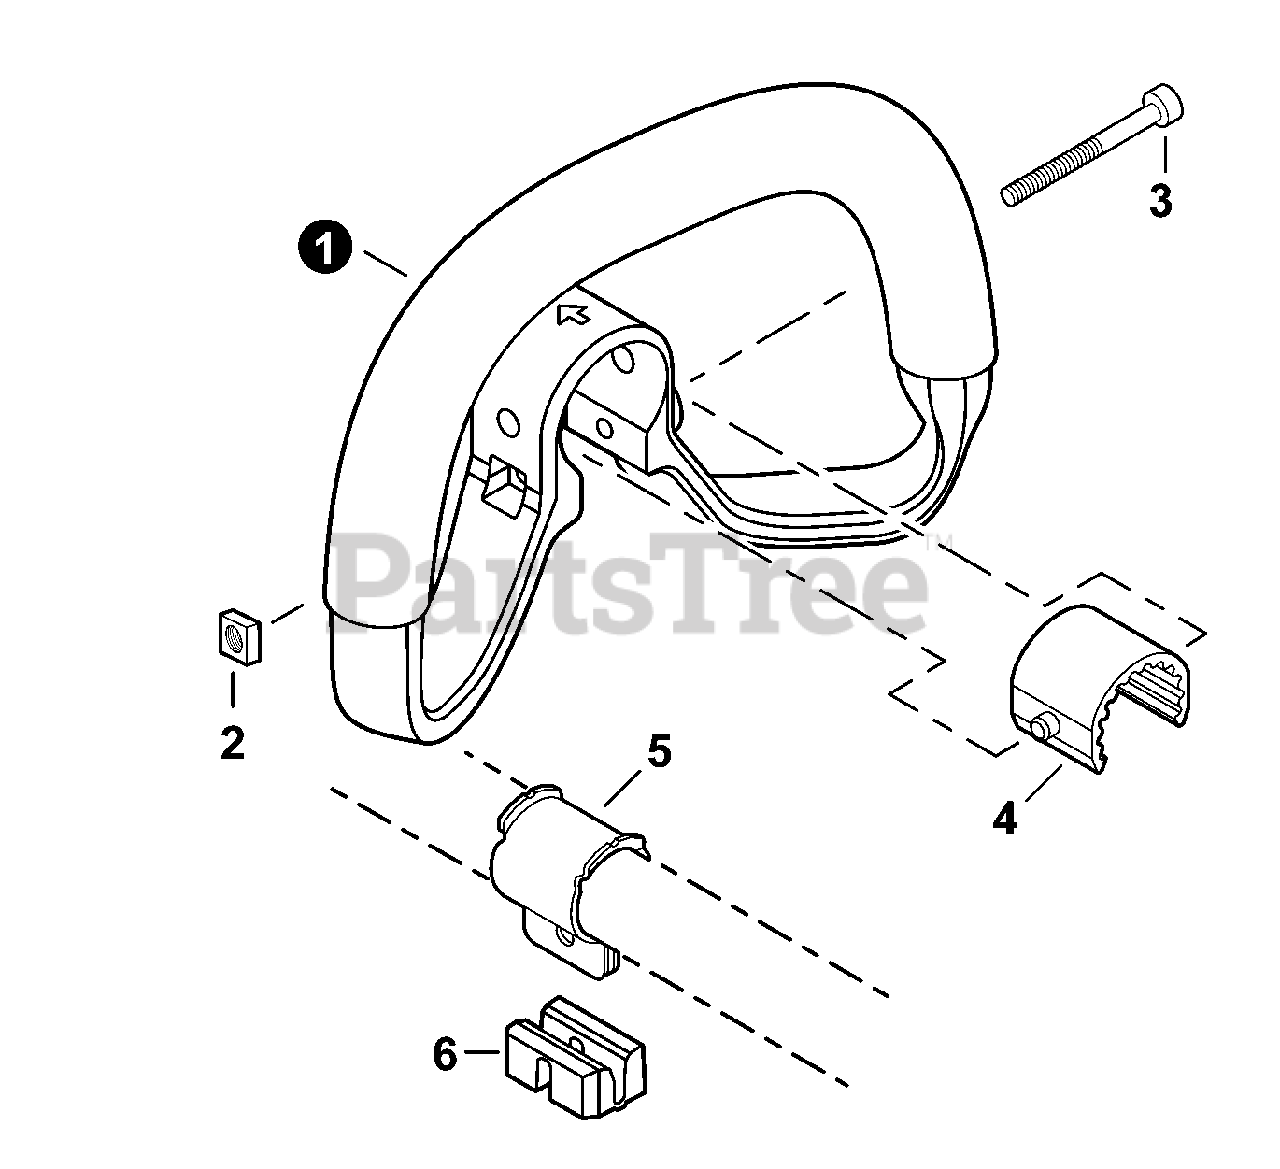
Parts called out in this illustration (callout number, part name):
1	HANDLE, SUPPORT
3	BOLT 5×45
4	CUSHION
5	BRACKET, MOUNTING
